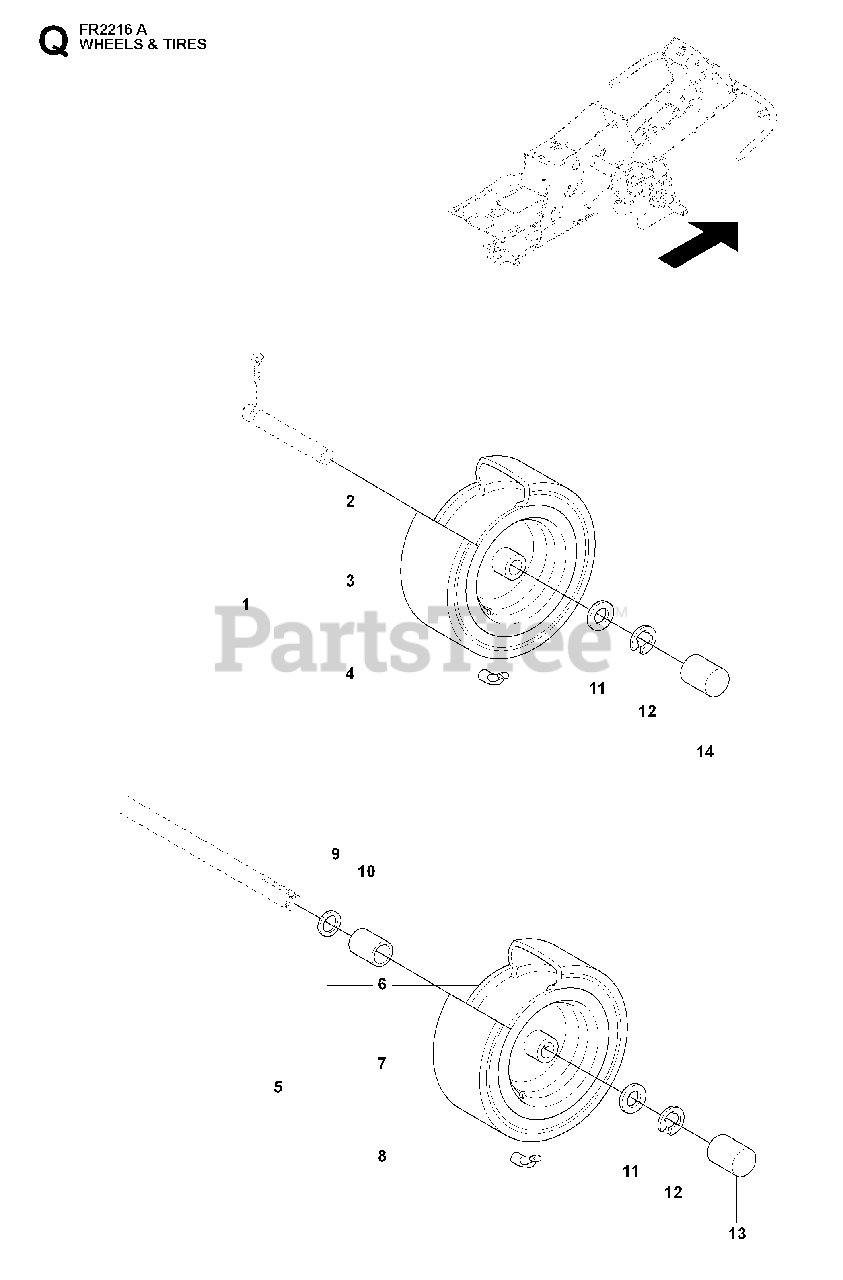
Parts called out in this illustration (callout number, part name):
6	RP RIM
10	SPACE SLEEVE
12	RETAINING RING
